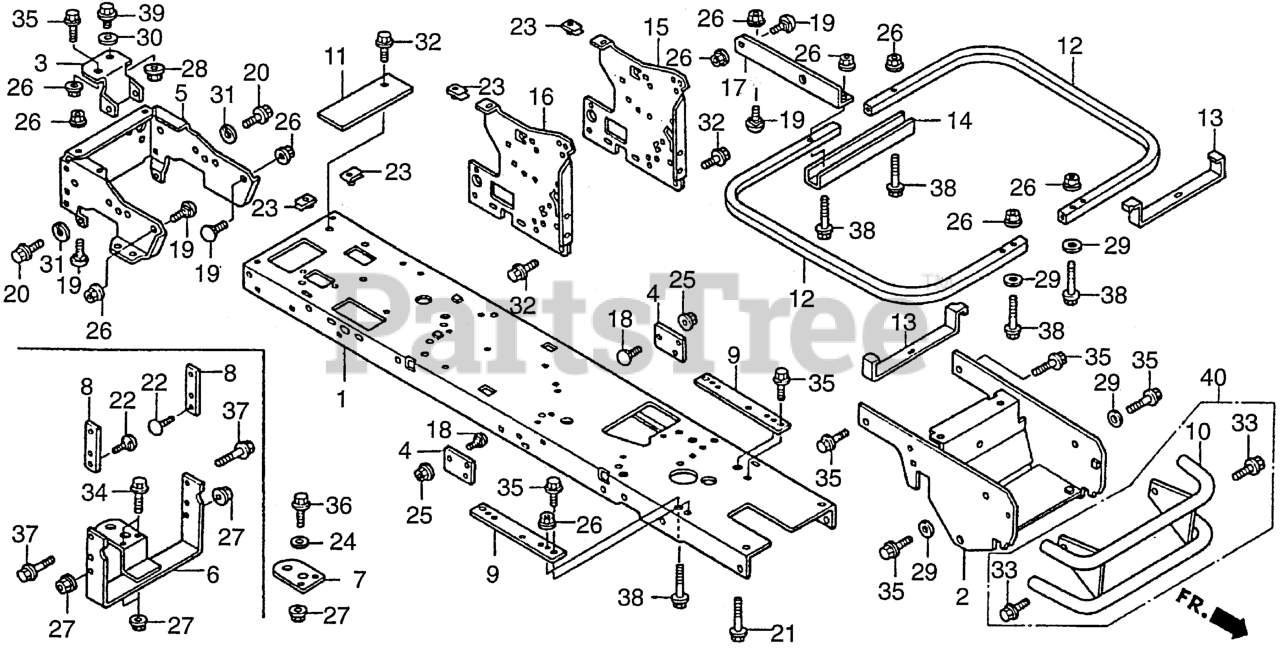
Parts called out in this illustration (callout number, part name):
2	FRAME, FR. AXLE
3	BRACKET, TRANSMISSION
4	PLATE, RR. DECK LINK
5	HITCH, RR.
7	HITCH, SUB-TRAILER
9	PLATE, ENGINE MOUNTING
10	GUARD, FR.
11	COVER, MAINTENANCE
12	PIPE, FLOOR
13	PLATE, FLOOR
14	HOLDER, FLOOR PIPE
15	FRAME, RR.
16	FRAME, RR.
17	STIFFENER, RR. FRAME
18	BOLT, SPECIAL (8X20)
19	BOLT, SPECIAL (9X15)
21	BOLT, FLANGE (5/16"X22)
23	NUT, CLIP (6MM)
24	WASHER, PLAIN (8MM)
25	NUT, FLANGE (8MM)
26	NUT, FLANGE (8MM)
27	NUT, FLANGE (8MM)
28	NUT, FLANGE (10MM)
29	WASHER, PLAIN (8MM)
30	WASHER, PLAIN (10MM)
32	BOLT, FLANGE (8X14)
33	BOLT, FLANGE (8X16)
35	BOLT, FLANGE (8X18)
36	BOLT, FLANGE (8X18)
38	BOLT, FLANGE (8X35)
39	BOLT, FLANGE (10X20)
40	GUARD, FR.
